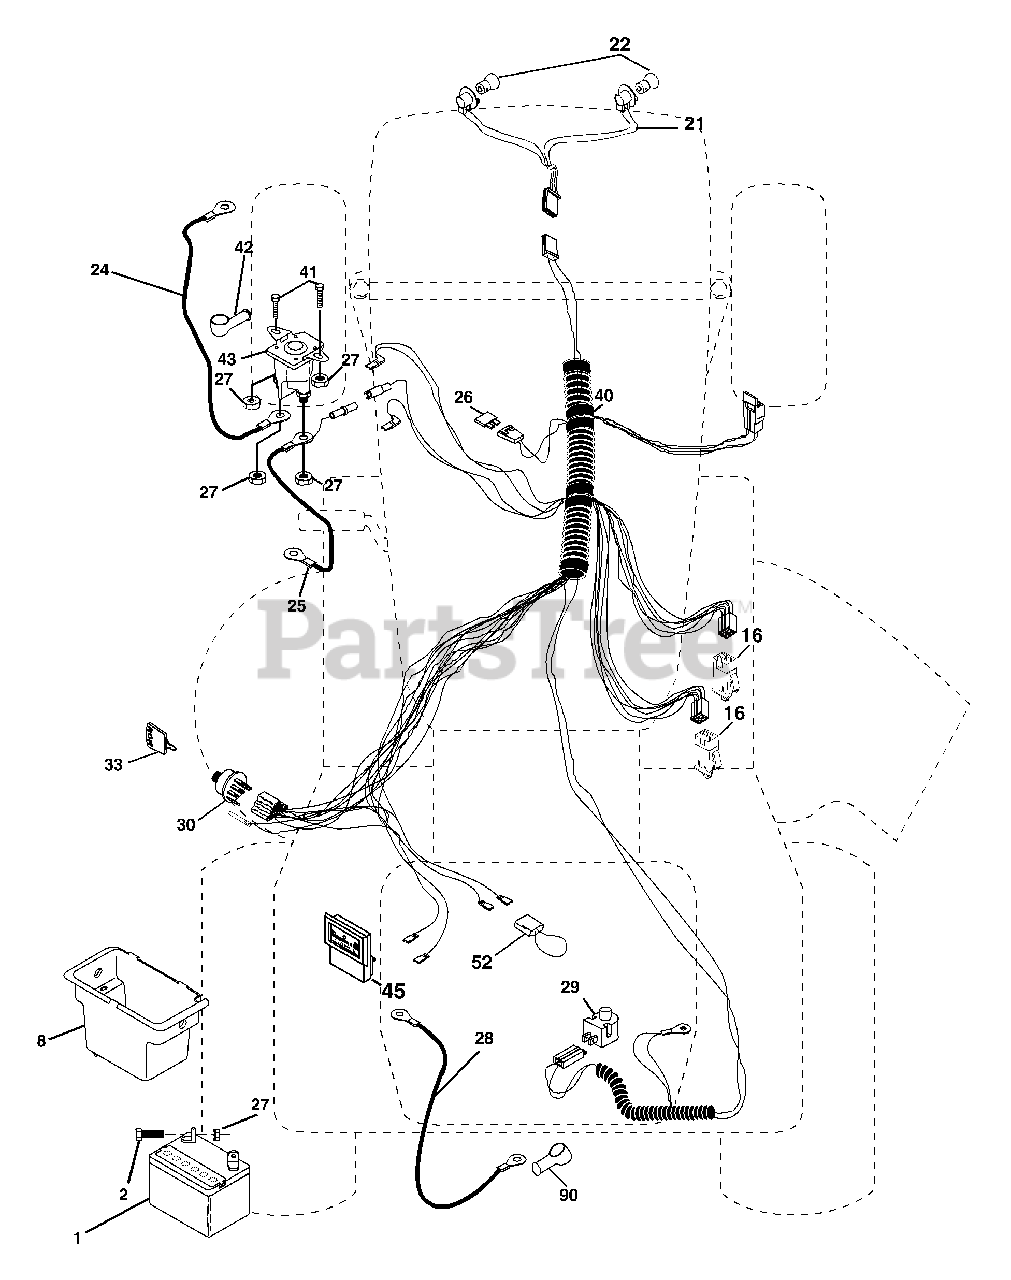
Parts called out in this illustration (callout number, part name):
1	Battery 12 Volt 25 Amp
2	Bolt Hex Hd 1/4-20 Unc x 3/4
8	Box Battery
16	Switch Interlock
21	Harness Asm Light W/4152J
22	Bulb Light #1156
24	Cable Battery 6 Ga 11"red
25	Cable Battery 6 Ga w/16 wire,red
26	Fuse 20 AMP
27	Nut Keps Hex 1/4-20 Unc
28	Cable Ground 6 Ga 12" black
29	Switch Plunger
30	Switch Ign
33	Key Ign
40	Harness Ign
41	Bolt Blk Fin Hex 1/4-20 x 1/2
42	Cover Terminal Red
43	Solenoid
45	Ammeter
52	Protection Wire Loop
90	Cover Terminal
